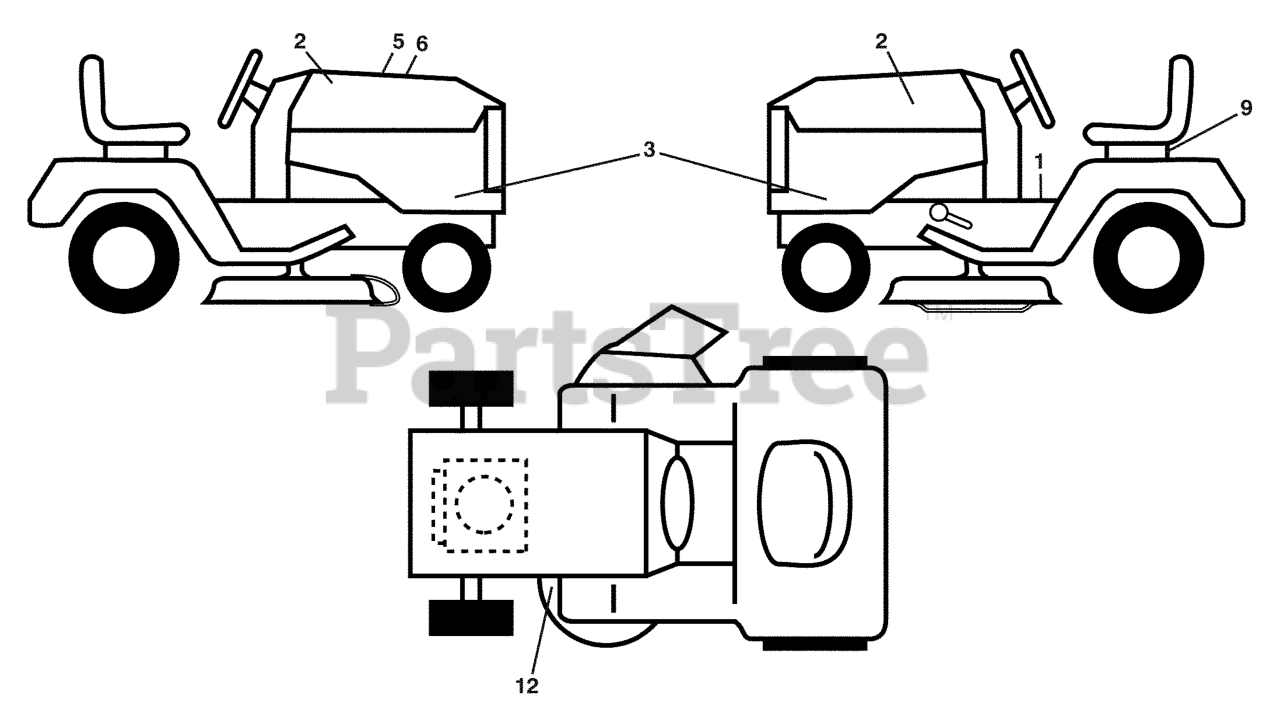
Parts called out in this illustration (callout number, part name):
1	DECAL.FENDER.WARNING.ENG
2	RP EMBLEM, HOOD
3	DECAL.PNL.SD.YTH21K46.HUSQ.KOH
5	DECAL.WARNING.CUST.RESP.E85.
6	DECAL.REPLACEMENT.96043008500
9	DECAL BTRY SYMBOLS
12	DECAL V BELT SCHEMATIC
